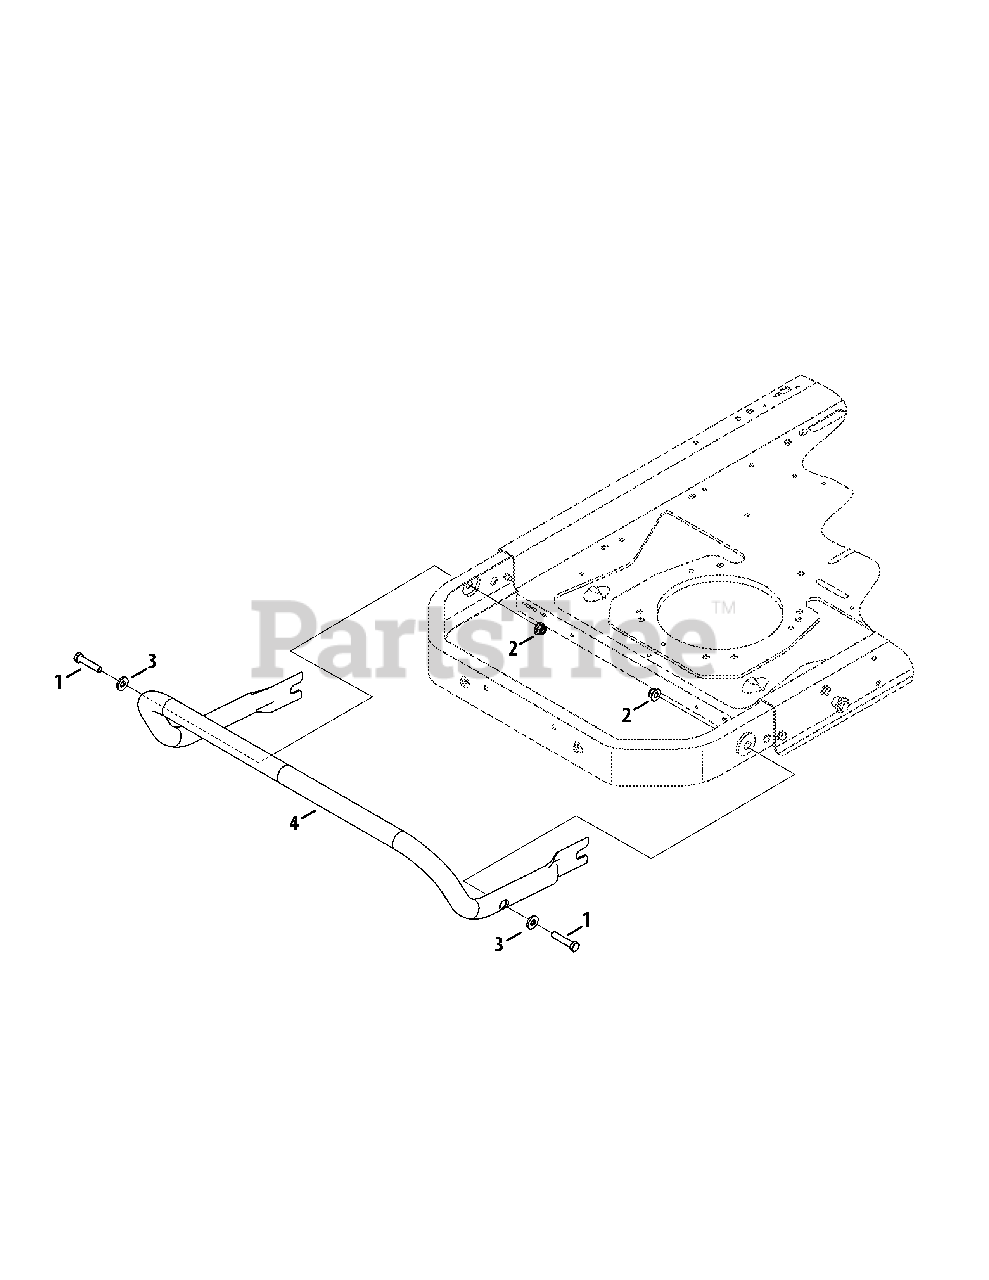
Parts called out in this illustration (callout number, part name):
1	Hex Cap Screw, 3/8-16 x 1.75
2	Flange Lock Nut, 3/8-16
3	Flat Washer, .406 x .875 x .105
